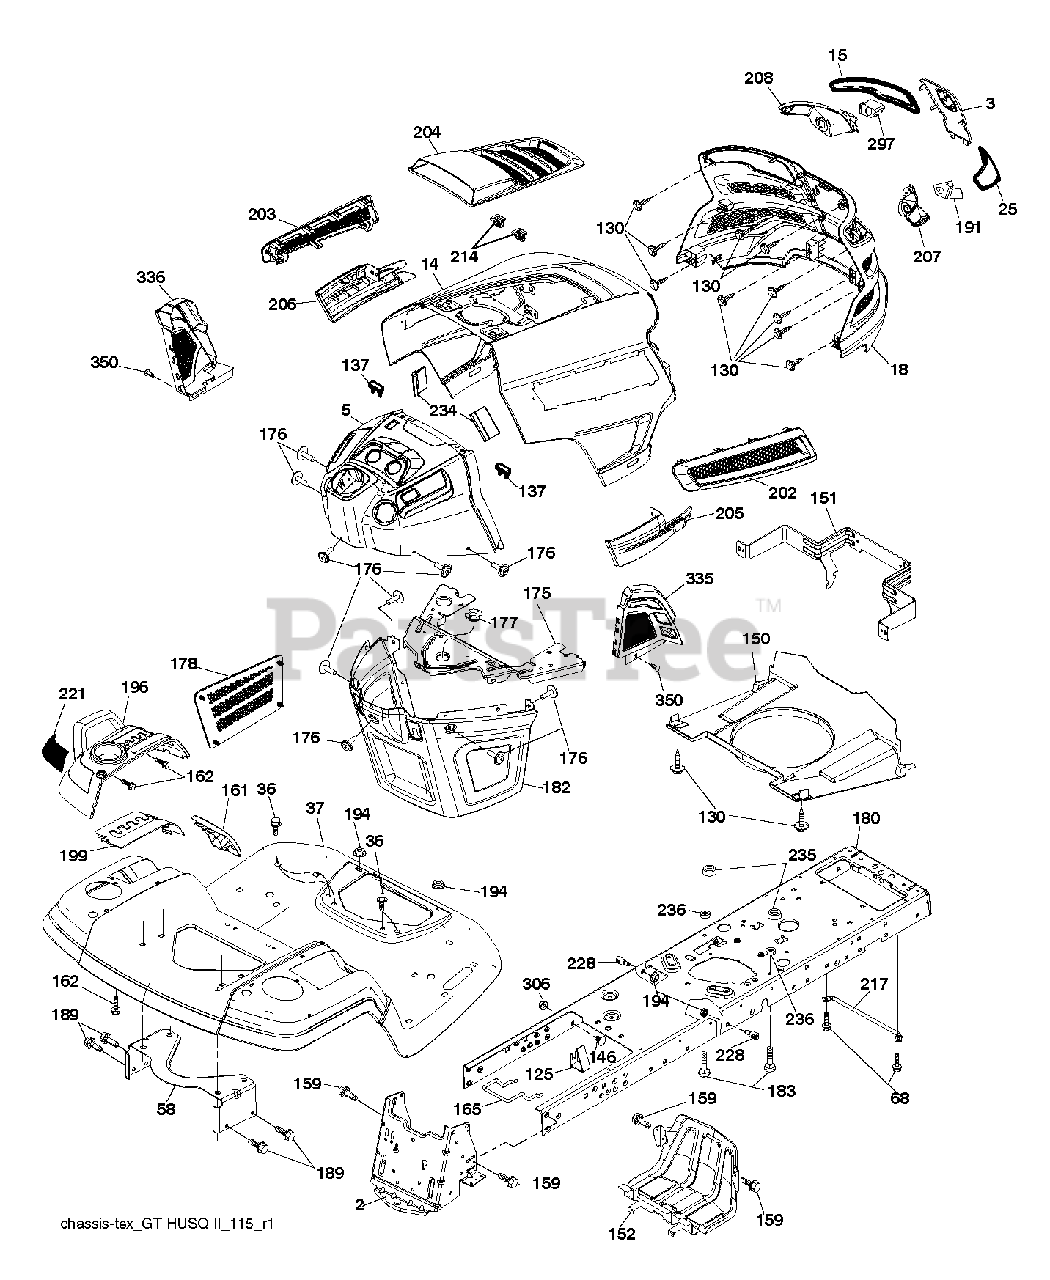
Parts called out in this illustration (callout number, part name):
2	DRAWBAR.STGT
3	APPLIQUE.SUBASM.GT.HUSQ.II
5	DASH.UPP.GT2.DUAL.RD.PTO.MCHOK
14	HOOD.ASM.HUSQVARNA.GT.TEX.ORAN
15	LENS.HEADLIGHT.LH.GTII.2011
18	GRILLE.SUBSTRATE.2011.
25	LENS.HEADLIGHT.RH.GTII.2011
36	SCREW 5/16"
37	FENDER.PNT.TX.GT.CH/FW/DL.HUSQ
58	BRKT.SUPPORT.FNDR/TANK
68	SCREW LT
125	CLIP.FUEL.LINE
130	SCREW.#10 X 0.750.BOS
137	BUMPER DASH
146	BOLT.RDHD.SHT.SQNK.3/8-16X5/8
150	AIR.DUCT.GTV.BLACK
151	BRACKET.PIVOT.HOOD.GT.HUSQ.II
152	SHIELD.BROWNING.PNT.GT.V2
159	SCREW, 3/8-16X3/4
161	CONSOLE.WINDOW.FUEL.HUSQ.GT
162	SCREW.HI-LO.CONSOLE
165	SUPPORT.TANK.REAR.B/TE
175	PLATE.CROSSMEMBER.HUSQ
176	SCREW.#10-24X5/8.RN.QU
177	BUSHING, STEERING
178	CARGO.ASM.NET.TXGT.W/C
180	CHASSIS.TEX.BOLTED
182	DASH.LOWER.COMMON.12V.ADAPTOR
183	BOLT.5/16-18X1-1/4 FULL THD
189	SCREW
191	INSERT.REFLECTIVE.RH.HUSQ.GTII
194	NUT LOCK HEX FLANGE 5/16-18
196	CONSOLE.ASM.DECKLIFT.HUSQGT.DL
199	PLATE.DECK.LIFT.HUSQVARNA.GT
202	VENT.SIDE.RH.GT.HUSQ.II.
203	VENT.SIDE.LH.GT.HUSQ.II.498
204	VENT.TOP.HUSQ.GT2
205	SIDE.TRIM.RH.GT.HUSQ.II
206	SIDE.TRIM.LH.GT.HUSQ.II.GRAY
207	BEZEL LIGHT.RH.GT.II.MYLAR
208	BEZEL LIGHT.LH.GT.II.MYLAR
214	CLIP.RETAINER.TINNER.
217	ROD.PIVOT.HOOD
221	REFLECTOR.LH.TEX GT HU
228	STUD.FASTNER.W/ANTI-ROTATE
234	BUMPER.HOOD.TEX.HUSQVARNA
235	SPACER FENDER
236	NUT.CENTERLOCK.5/16-
297	INSERT.REFLECTIVE.LH.HUSQ.GTII
306	NUT LOCK FLG 3/8-16 UNC
335	COVER.LOWER.DASH.RH.BLACK
336	COVER-LH.LOWER.DASH.GT2.BLACK
350	CLIP.X-MAS.TREE
